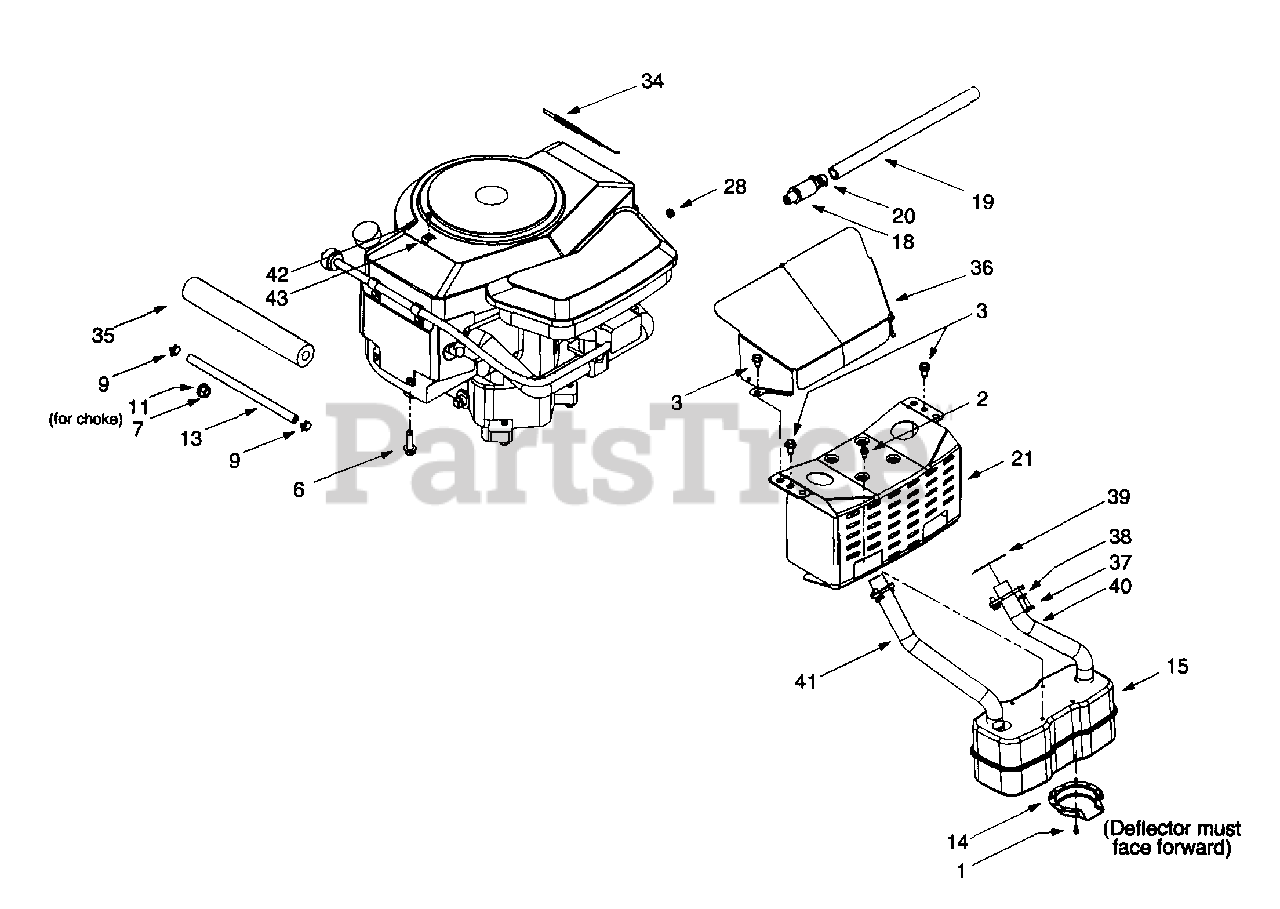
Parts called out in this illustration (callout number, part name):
1	Self-tapping Screw, #8-32 x .375
2	Self-tapping Screw, 1/4-20 x .5
3	Self-tapping Screw, 5/16-18 x .625
6	Self-tapping Screw, 3/8-16 x 1.25
7	Hex Nut, 3/8-16
9	Hose Clamp
11	Lock Washer, .406 x .875 x .059
13	Fuel Line Hose
14	Muffler Deflector
15	Muffler, Twin Inlet
18	Oil Drain Valve
19	Oil Drain Hose
20	Oil Drain Cap
28	Hex Sems Nut, 1/4-20 (For starter cable)
34	Throttle Cable (OHV V-Twin & Opposed Twin)
35	Foam, .625 x 1.5 x 10 (Fits over fuel line)
37	Hex Cap Screw, 1/4-20 x .620 (Grade 5)
38	Lock Washer, 1/4
39	Exhaust Gasket (Opposed Twin)
40	LH Exhaust Pipe (Opposed Twin)
41	RH Exhaust Pipe (Opposed Twin)
42	Screw, #10-16 x .5
43	Clamp, 9/16
